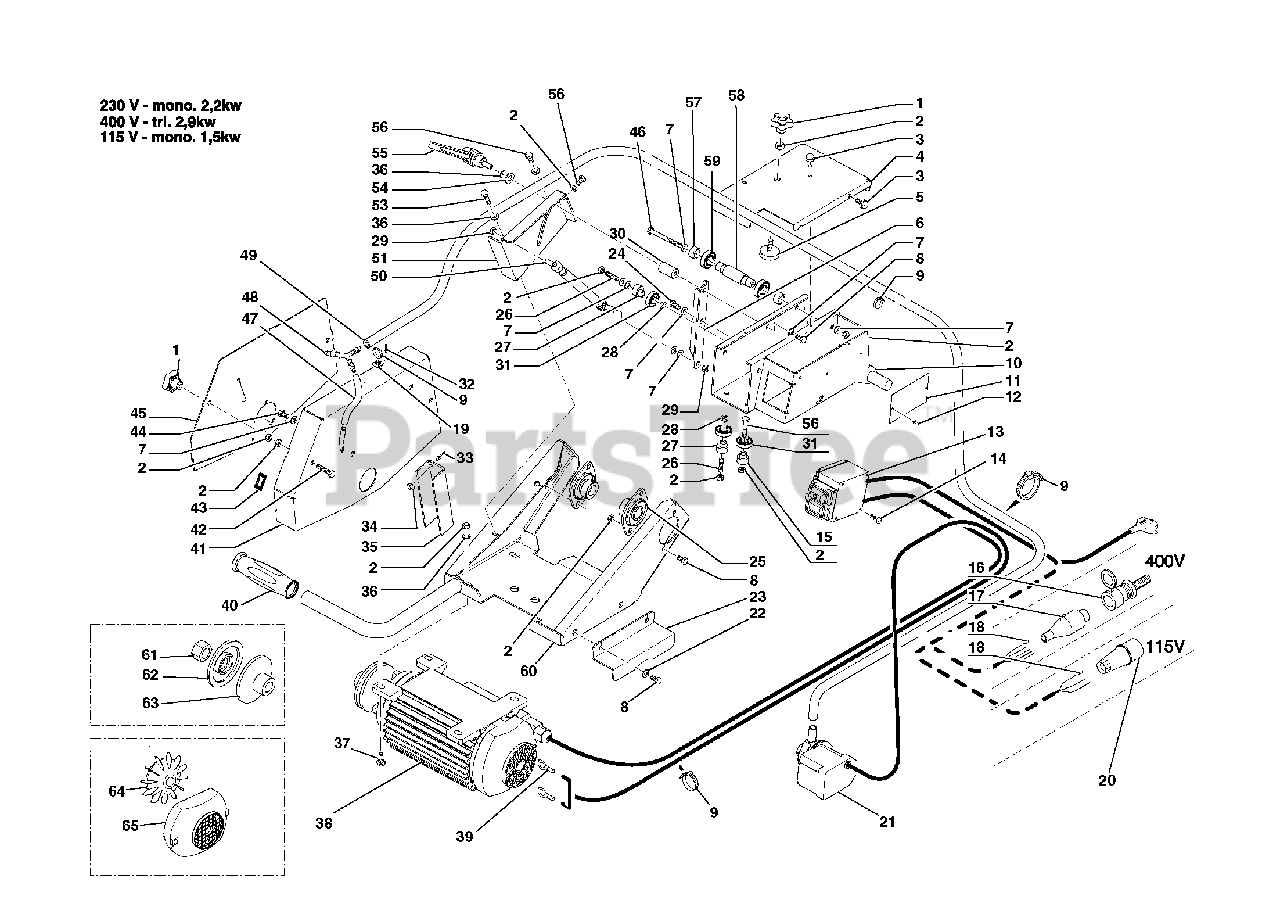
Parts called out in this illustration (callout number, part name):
2	HEXAGON NUT
3	VIS TH 8/8 5X10 BICHROM/
5	SUPPORT ANTIVIBRATOIRE/
7	WASHER
8	SCREW EHHM
9	COLLIER SES QUICK 185/46/SL-C
16	PROLONG. 3P+N+T 16A 6H/
17	FICHE 16A 380V 3P+N+T 6H/AVEC
18	COSSE EMBOUT 1.5MM/LEG 37664
19	COLLIER SUPPORT D/19/
20	FICHE 2P+T 32A 110V 4H/PRESSE
21	PUMP230V 50Hz 2.5m Black TS
21	PUMP110V 50Hz 2.5m Black TS
31	BALL BEARING
34	RONDELLE ACIER M4 BICHRO/
36	RONDELLE ACIER L8 BICHRO/
39	COSSE BLEUE PLAG D4 BFM4/
53	SCREW EHHM
59	BALL BEARING
60	MOTOR SUPPORT/TS350KL
